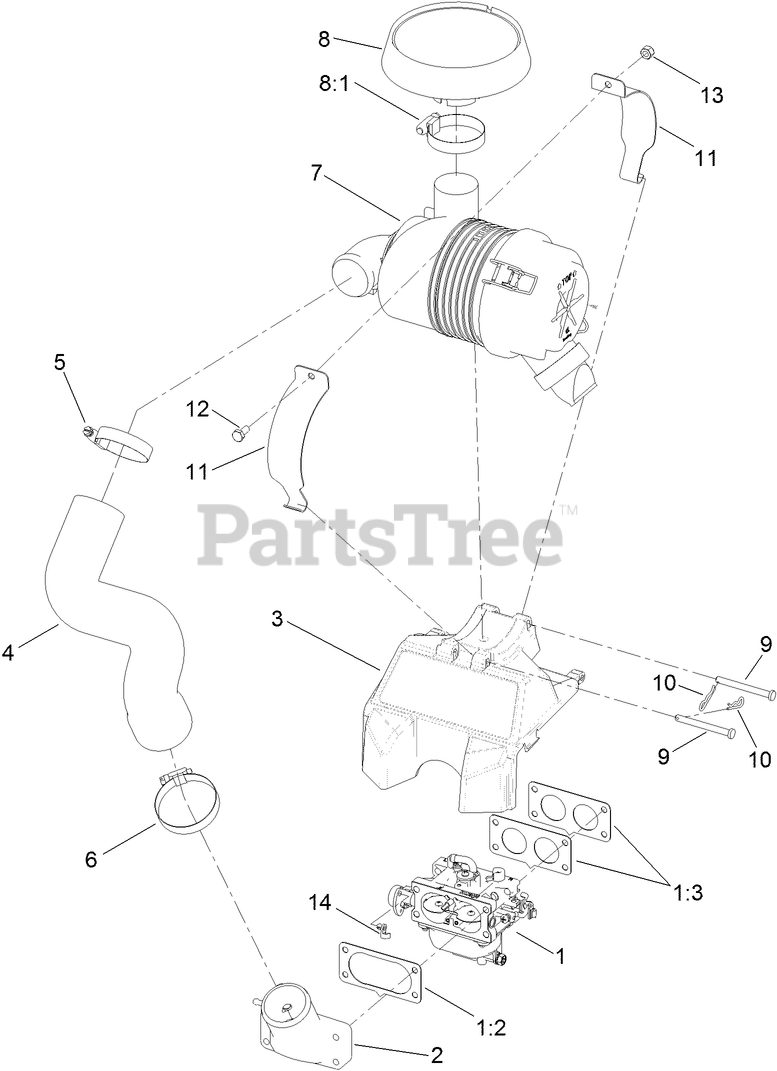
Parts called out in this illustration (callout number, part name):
1	CARBURETOR REPLACEMENT KIT ASM
1:2	GASKET-CARBURETOR
1:3	GASKET-CARBURETOR
2	MANIFOLD-INTAKE
3	SUPPORT-FILTER
4	HOSE-INTAKE
5	CLAMP-HOSE
6	CLAMP-HOSE
7	AIR CLEANER ASM
8	RAIN CAP KIT
8:1	CLAMP-HOSE
9	PIN-CLEVIS
10	PIN-COTTER
11	STRAP-CANISTER, AIR
12	SCREW-HH
13	NUT-HEX
14	CLIP-LINKAGE
